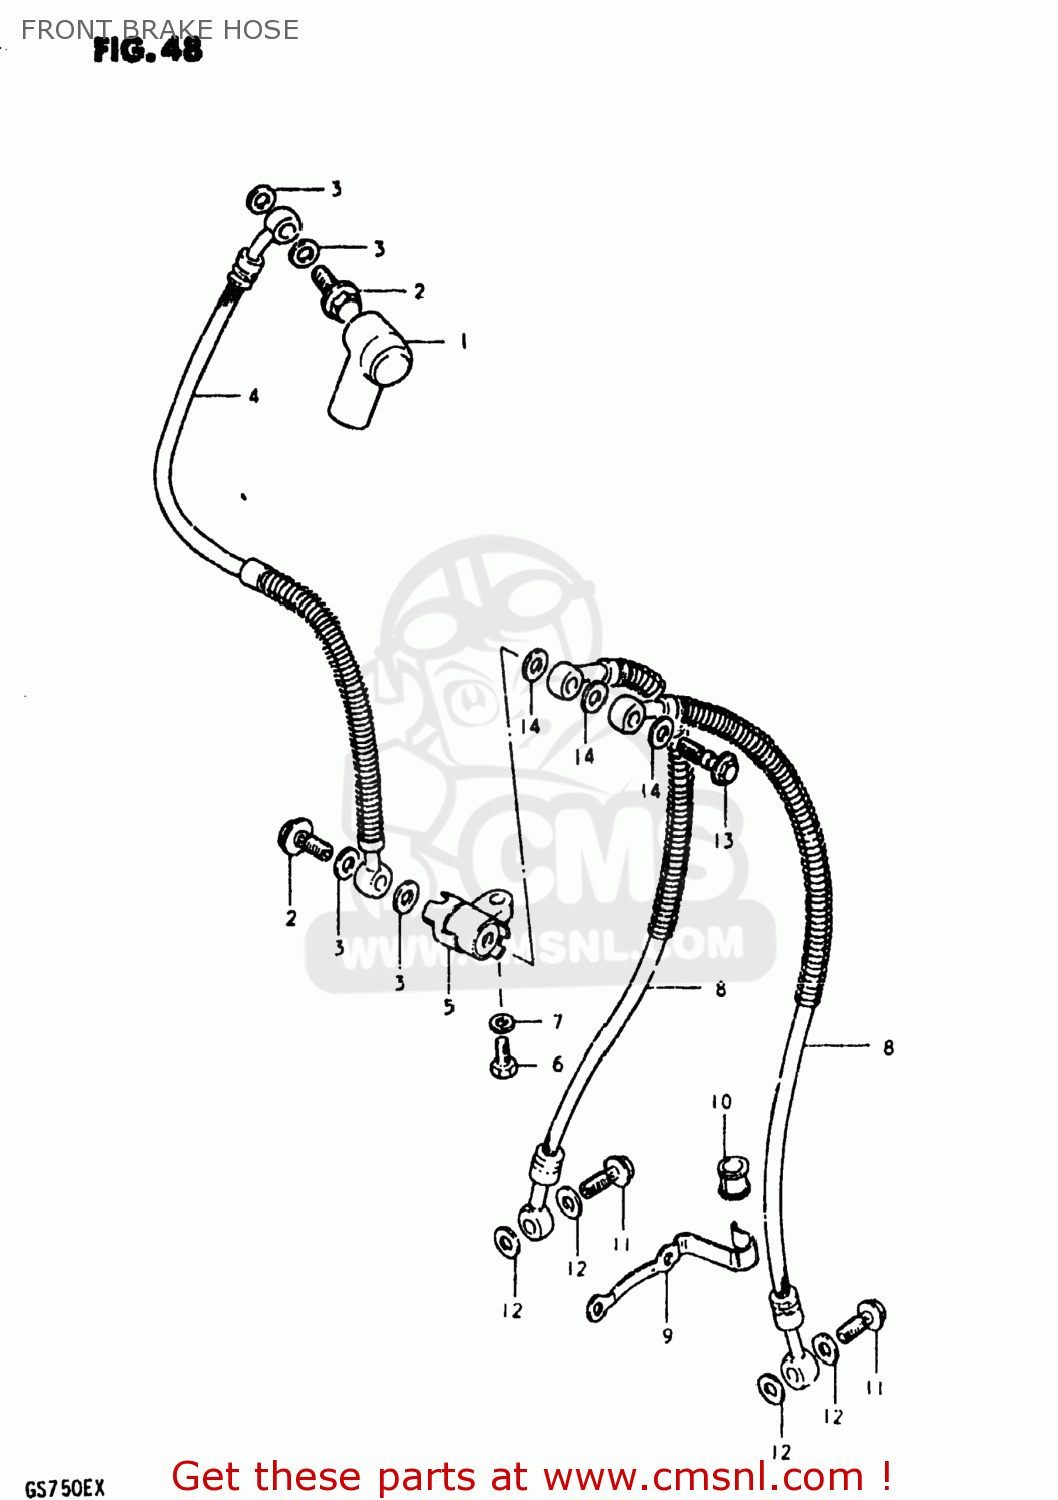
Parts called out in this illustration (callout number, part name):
1	BOOT,MASTER CYLINDER
2	BOLT,UNION
3	WASHER
4	HOSE,FRONT BRAKE
5	JOINT,BRAKE HOSE
6	BOLT
7	LOCK WASHER
8	HOSE,BRAKE NO.2
9	GUIDE,BRAKE HOSE NO.2
10	BUSH,BRAKE HOSE GUIDE,NO.2
11	BOLT,UNION
12	WASHER
13	BOLT,UNION
14	WASHER
